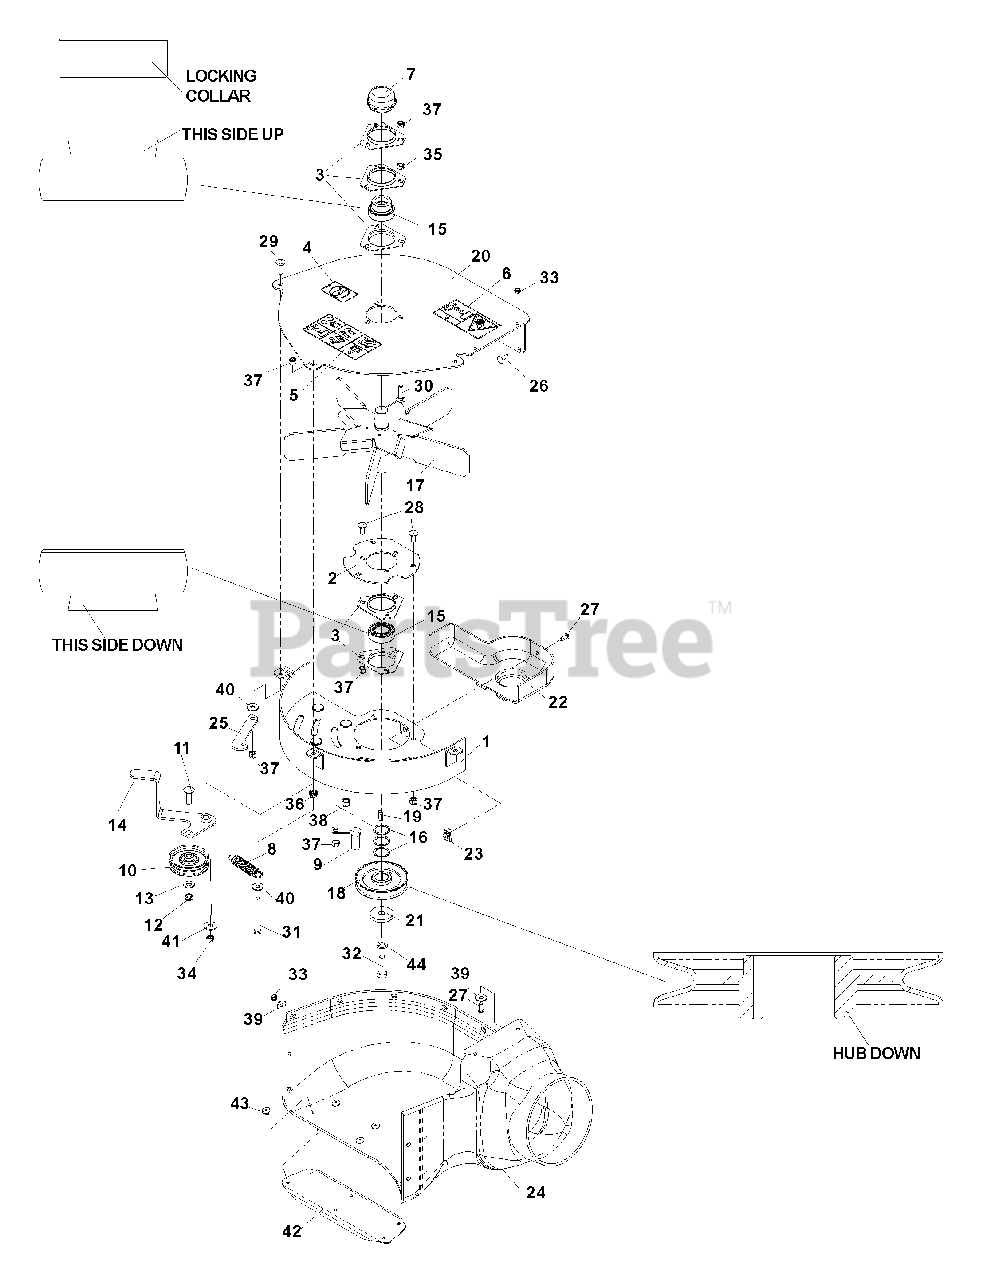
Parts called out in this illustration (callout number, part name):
1	FLOOR WELDMENT
2	BEARING PLATE
4	DECAL, NO STEP
5	DECAL, WARNING
6	DECAL, SEVERING
7	GREASE CAP
9	BELT GUIDE
11	RHSNB, 3/8 -16 x 1 1/2,
12	NUT, 3/8 -16, JAM NYLOC
13	WASHER, 3/8 , SAE
16	BUSHING, MACHINE, 18 GA
17	FAN WELDMENT
18	SHEAVE, 4"
21	WASHER, HEAVY
22	PULLEY SHIELD
23	RETAINER, 1/4C, "U" TYPE
24	BLOWER HOUSING
25	KEEPER, IDLER
26	RHSNB, 1 1/4 -20 x 3/4 GR2
27	SCREW, 1/4 -20 x 5/8, SKT HD
28	RHSNB, 5/16 x 3/4
29	RHSNB, 5/16 -18 x 1,
30	RHSNB, 5/16 C x 1 1/4
31	HCS, 5/16 -18 x 2 3/4,
32	HCS, 7/16 -20 x 1 1/2,
33	NUT, 1/4C, THIN NYLOC
34	NUT, 5/16 C, CENTERLOCK
35	NUT, 5/16 C
36	NUT, 5/16 C
37	NUT, 5/16 C, NYLOC
38	NUT, 3/8C, NYLOC
39	WASHER, 1/4
40	WASHER, 5/16
41	WASHER, 3/8
42	BLOWER SUPPORT
44	LOCKWASHER, 7/16
